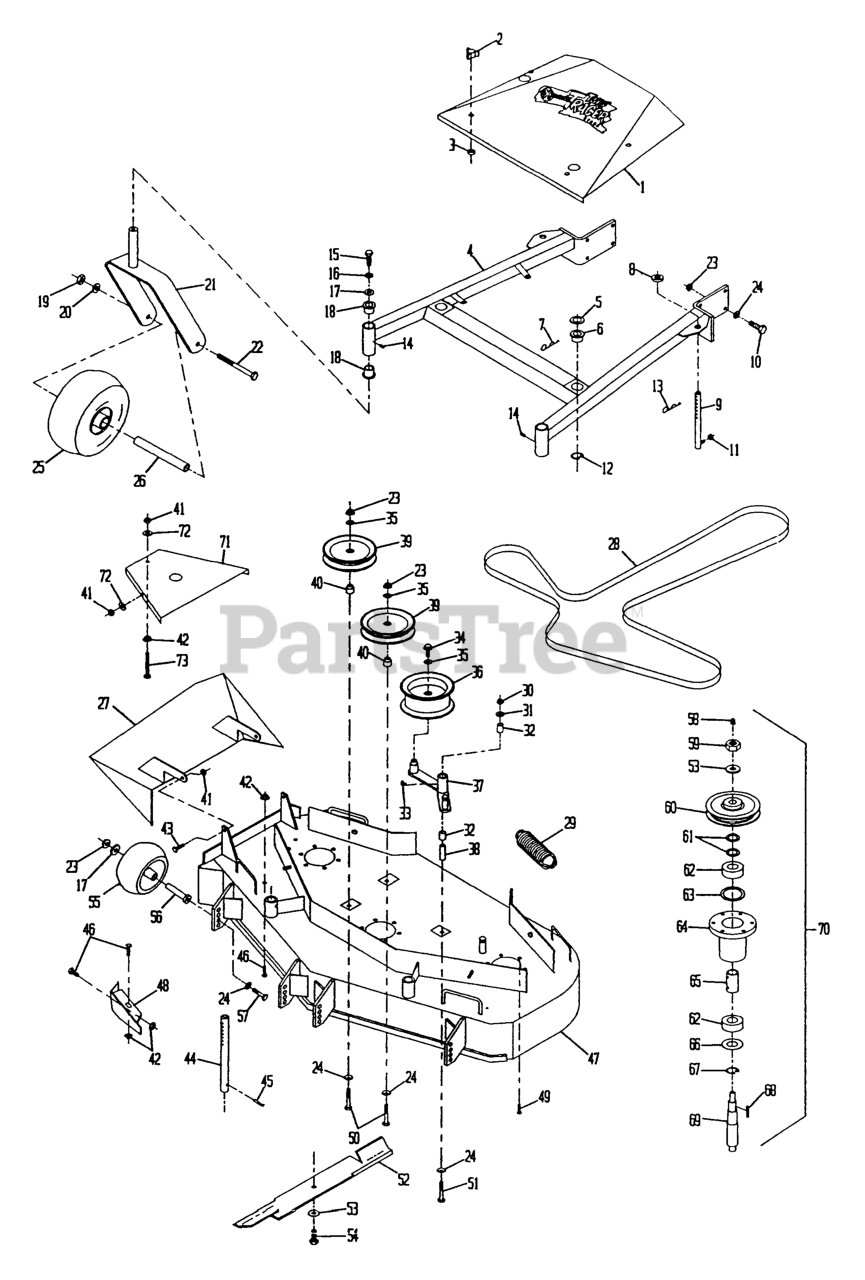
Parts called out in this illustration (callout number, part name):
2	KNOB-3 PRONG
4	DECK SUPPORT W/BSHGS 48"
5	WASHER-FLAT
6	BUSHING-DECK
13	PIN,HAIR COTTER
18	BEARING-FLANGED
28	BELT - V, B
32	SLEEVE-BEARING
38	BUSHING-PIVOT, IDLER
39	PULLEY-IDLER
40	BUSHING-IDLER
44	ROD,DECK SUPPORT
47	ASM,DECK W/DECALS TTHP/MH
49	SCRW,TPTTE HH
51	SCREW-HH
53	WASHER-SPRING
55	ROLLER-SCALP, ANTI
56	BUSHING-ROLLER
60	SHEAVE,W/HUB 5.72
61	WASHER-SPACER
62	BEARING,HD SPINDLE
64	HOUSING,BEARING
65	SPACER,BEARING
66	SEAL,MECHANICAL DUST
67	RING,SNAP WLDS N5000-244
68	KEY-RECTANGLE
73	BOLT,TAP HH
